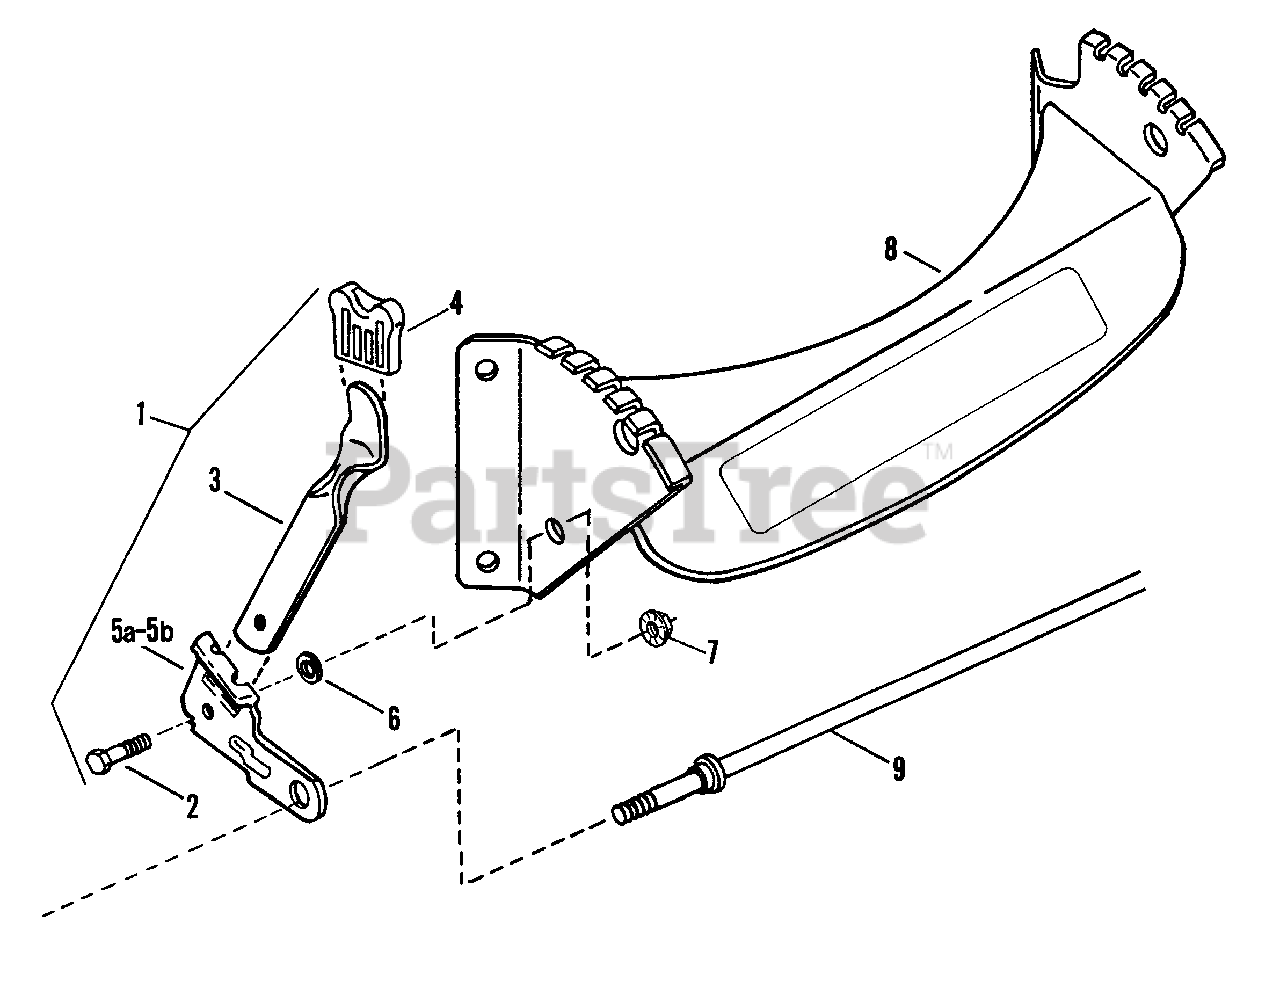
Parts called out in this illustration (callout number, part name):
1	ARM ASSEMBLY, Left Wheel
2	BOLT, 5/16 - 18 Shoulder
3	LATCH, Height
4	GRIP, Latch
5A	ARM, Left Wheel
5B	ARM, Right Wheel
6	RETAINER, 5/16 Bolt
7	NUT, 5/16 - 18 Hex Flange Lock
8	BRACKET, Front Wheel
9	AXLE
